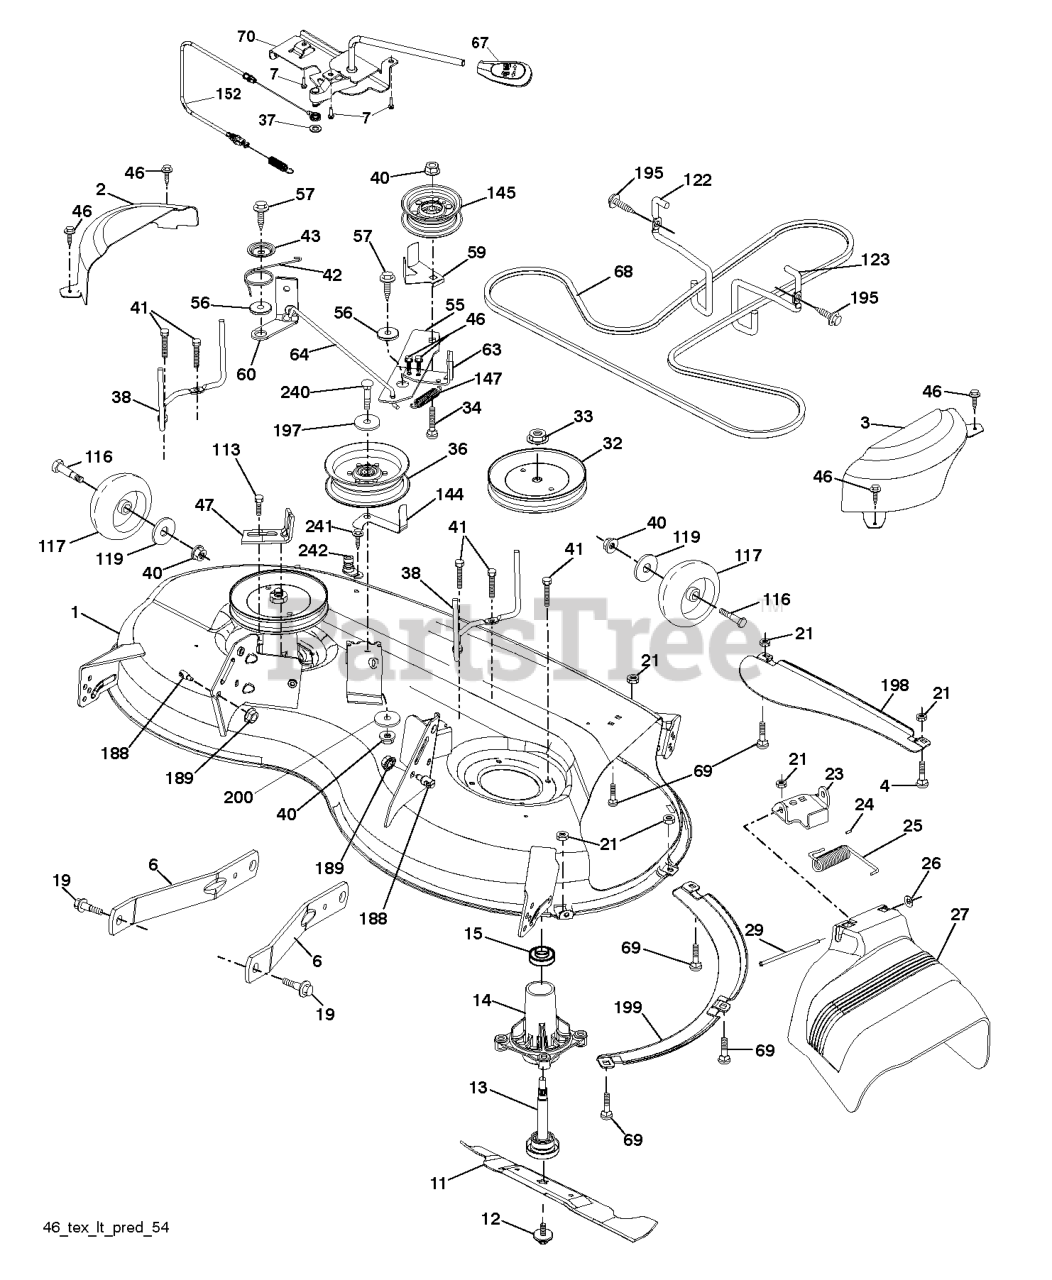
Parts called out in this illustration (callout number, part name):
1	SERVICE KIT KIT.SVC.DECK.WLD.4
2	COVER 46 XFAB TRACTOR LH MANDR
3	COVER 46 XFAB TRACTOR RH MANDR
4	Bolt, Hex Head 5/16-18 UNC x 3/4 (AYP part number)
6	ARM.SUSPENSION.MOWER.R
7	SCREW.#10 X 0.750.BOS (2 2)
11	BLADE.MOWER.46".HI.LIFT
12	SCREW.SEMS.7/16-20X1.HEX.HEAD
13	SHAFT ASM.MNDRL.N/GREASEABLE
14	HOUSING.MANDREL.4PT.
15	BEARING.MANDREL.TOP.EXTENDED
19	BOLT.SHOULDER
21	Locknut, Hex w/Insert 5/16-18 Unc
23	BRKT.DEFLECTOR.38"2005+
24	Cap Sleeve 80x 112 Blk Mower (AYP part number)
25	SPRING.TORSION.DEFLECT
26	Nut Push Phos & Oil (AYP part number)
27	SHIELD.DEFLECTOR.MOWER.46"BLAC
29	Rod Hinge 42" 6 75 Wlg (AYP part number)
32	PULLEY.MANDREL.5.438.PD
33	NUT.FLANGE.LOCK.TOP
34	Bolt Carriage 3/8-16 x 1-1/2 (AYP part number)
36	PULLEY.IDLER.2006
37	Washer 13/32 x 1-3/16 x 12 Gauge (AYP part number)
38	KEEPER.BELT.MANDREL.PULLEY
40	NUT LOCK FLG 3/8-16 UNC
41	BOLT.HEX.WASHR.HED.313-18X1.19
42	SPRING.TORSION.BRAKE
43	SRPING.TORSION.RETAINE
46	Screw Hex Thd Cut 1/4-20x5/8 T (AYP part number)
47	BRKT.CLUTCH.CABLE
55	IDLER.ARM
56	SPACER.RETAINER
57	SCREW 3/8-16X1
59	Guard TUV Idler (AYP part number)
60	ARM BRAKE MOWER RH 38"
63	ARM BRAKE MOWER
64	LINKAGE BRAKE
67	HANDLE.CLUTCH.CABLE.LT
68	V-BELT
69	Bolt, Carriage 5/16-18 UNC x 5/8 (AYP part number)
70	CLUTCH.ASM.MANUAL.YT.PREDATORQ
113	BOLT.5/16HEX.WHS.HD
116	BOLT.SHOULDER.3/8-16X3-5/8.
117	WHEEL.GAUGE.RALLY
119	Washer 13/32 x 1-1/4 x 12 Gauge (AYP part number)
122	KEEPER BELT ENGINE LH
123	KEEPER BELT RH
144	KEEPER.BELT.MOWER
145	PULLEY.IDLER.48"PRIMARY
147	SPRING RETURN
152	CABLE.MECHANICAL.CLUTCH
188	STUD.FASTNER.W/ANTI-ROTATE
189	NUT LOCK HEX FLANGE 5/16-18
195	SCREW, 3/8-16X3/4
197	Washer 13/32 x 13/16 x 12 Gauge (AYP part number)
198	BAFFLE CENTER FRONT
199	BAFFLE FRONT RH
200	WASHER.13/32 X 1 X 1/2.11GUARD
240	BOLT-HEX EAK
241	SCREW.TT.#10-32X.5.3/8.FLANGE
242	PORT.WASHOUT
